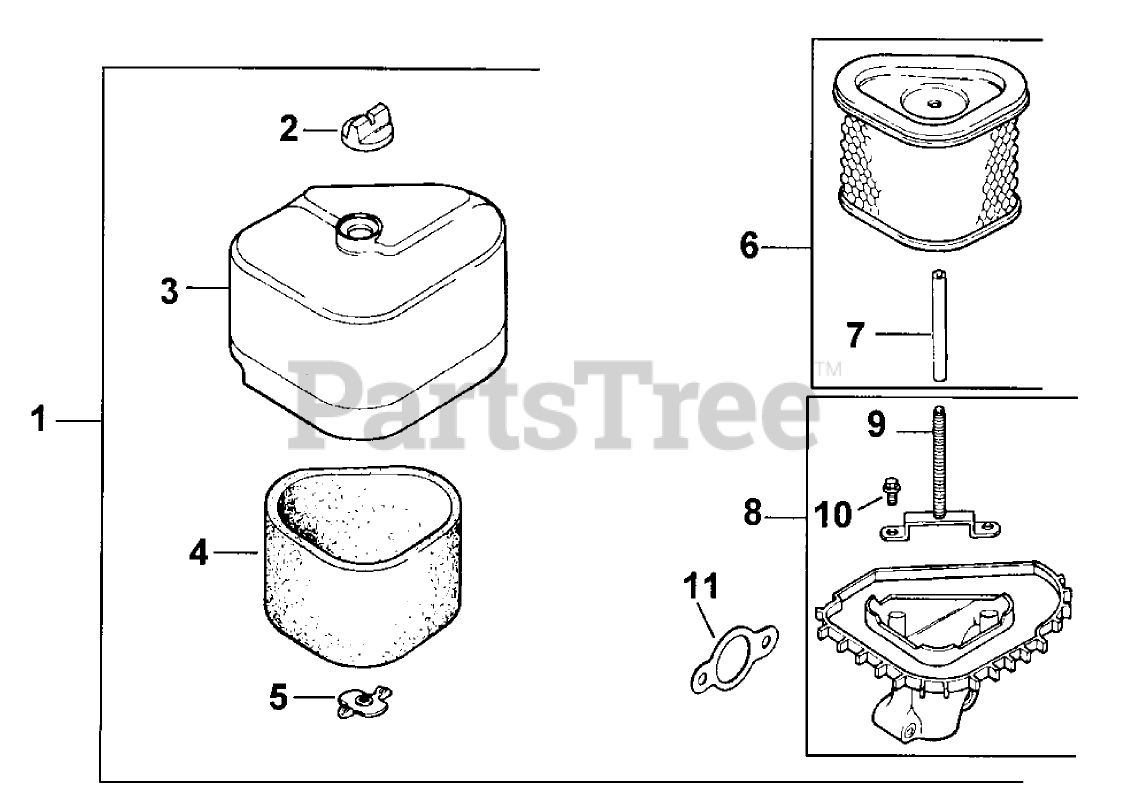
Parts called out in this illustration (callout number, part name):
1	Kit-Air Cleaner (Incl. Ref.# 2-11)
2	Knob-Cover
3	Cover-Air Cleaner
4	Precleaner-Element
5	Wingnut
6	Element-Air Cleaner (Incl. Ref.#7)
7	Seal
8	Base-Air Cleaner (Incl. Ref.#9, 10)
9	Stud-Mounting Plate
10	Screw
11	Gasket-Air Cleaner
